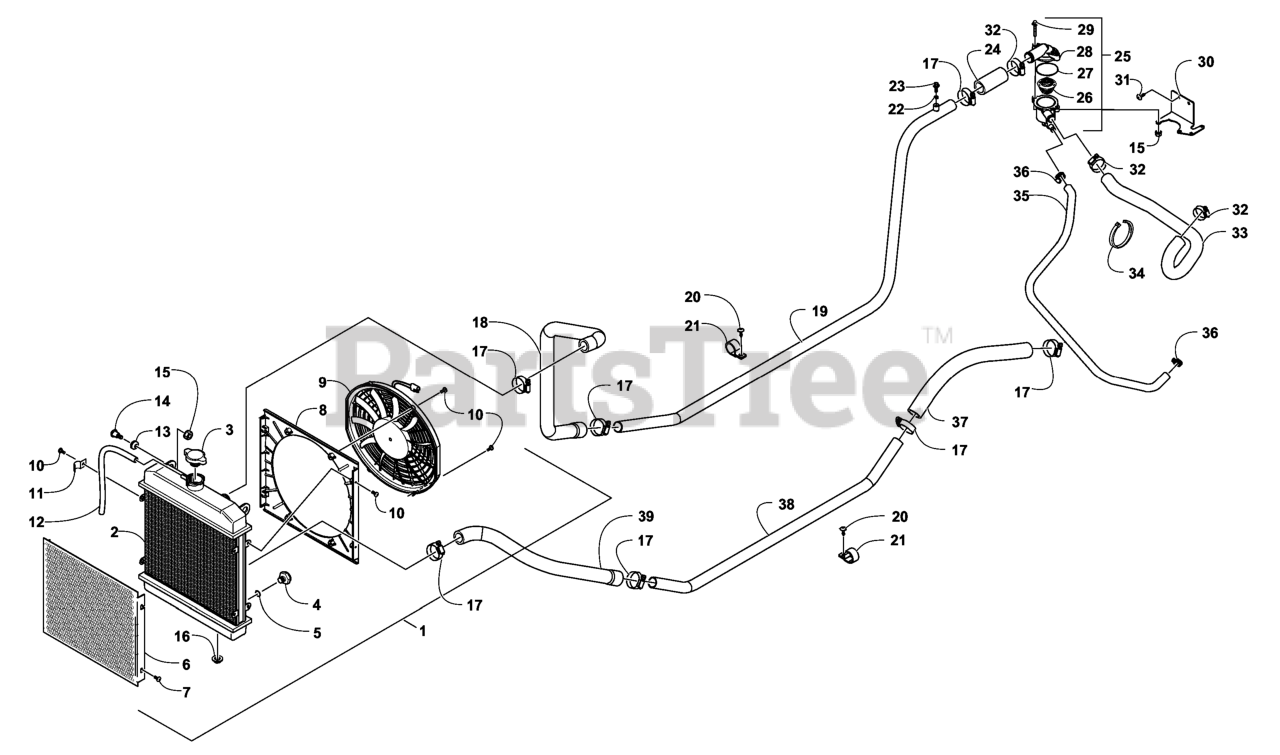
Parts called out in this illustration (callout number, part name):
1	RADIATOR ASM
2	RADIATOR
3	CAP-RADIATOR
4	PLUG-DRAIN, RADIATOR
6	SCREEN-RADIATOR
7	SCREW-TSPRH
8	SHROUD-FAN
9	FAN-RADIATOR
11	CLIP-HOSE
12	HOSE-GAS
13	GROMMET
14	BOLT-SHOULDER
15	NUT-HH, SEMS
16	BUSHING-STEM
17	CLAMP-WORM, HOSE
18	HOSE-RADIATOR, UPPER COOL
20	SCREW-TSTRH, SELFTAP
21	CLAMP-PIPE
23	Screw, Bleed
24	HOSE-COOLANT
25	HOUSING-THERMOSTAT
26	THERMOSTAT ASM
28	COVER-THERMOSTAT
29	BOLT-FLANGE
30	BRACKET-MOUNT,THERMOSTAT/
31	SCREW-HWH, SELFTAP
33	HOSE-COOLANT, THERMOSTAT
34	CABLE TIE
35	HOSE-COOLANT
36	CLAMP-HOSE
37	HOSE-COOLANT, LOWER ENGIN
38	PIPE-COOLANT, LOWER
39	HOSE-RADIATOR, LOWER COOL
